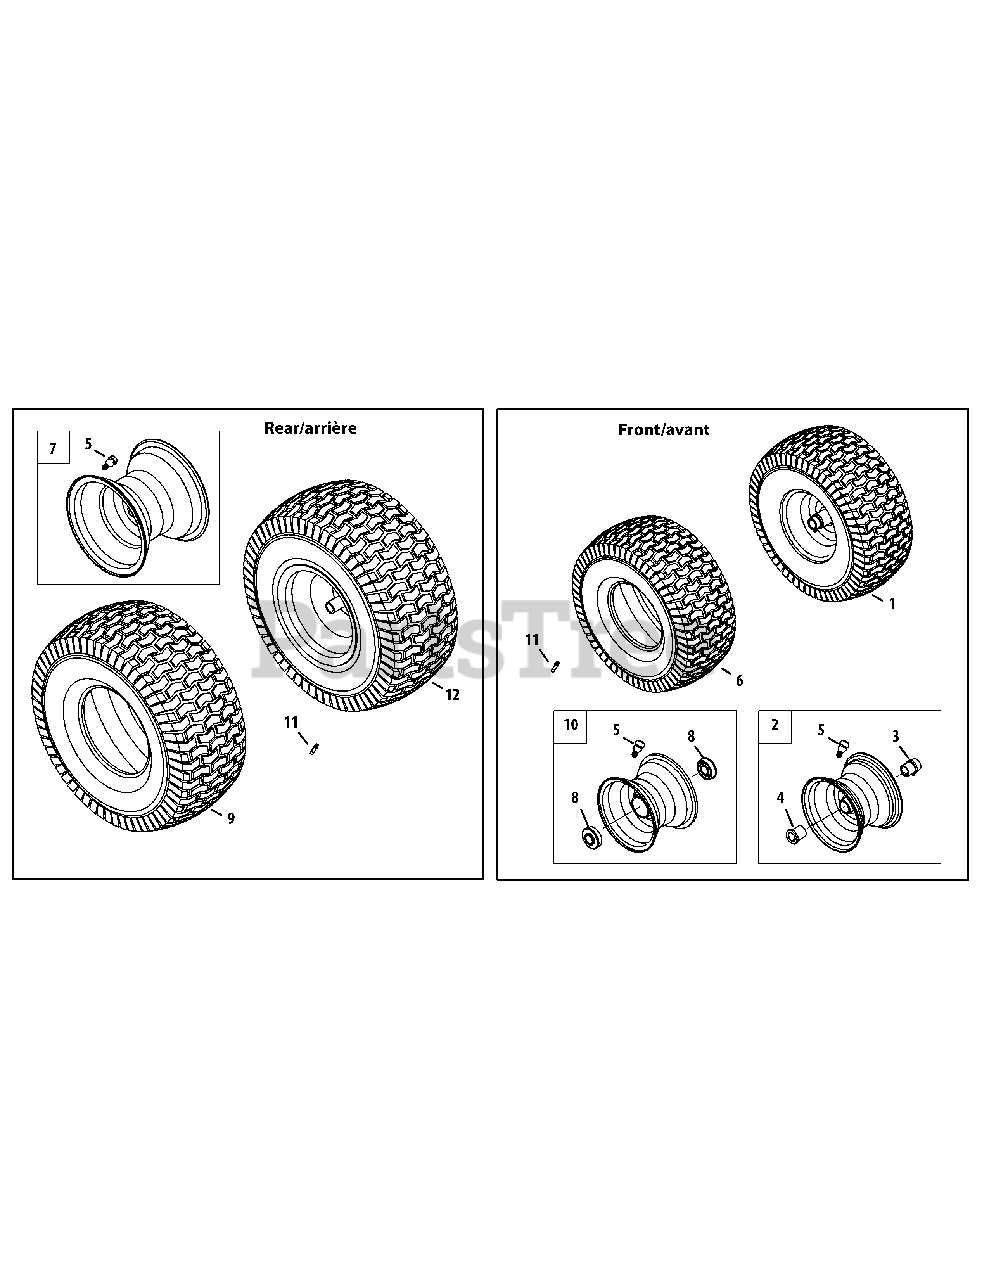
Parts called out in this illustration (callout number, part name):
1	Wheel Ass’y, 15 x 6 flange Bearing (Grey)
2	Rim Ass’y, flange Bearing (Grey)
3	Flange Bearing .760 ID w/fitting
4	Flange Bearing .760 x 1.0 x 1.20
5	Air Valve
7	Rim Ass’y, 8.0 x 7.0 x .750 (Grey)
9	Tire, 20 x 8 x 8 Square Shoulder
12	Wheel Ass’y, 20 x 8 (Grey)
